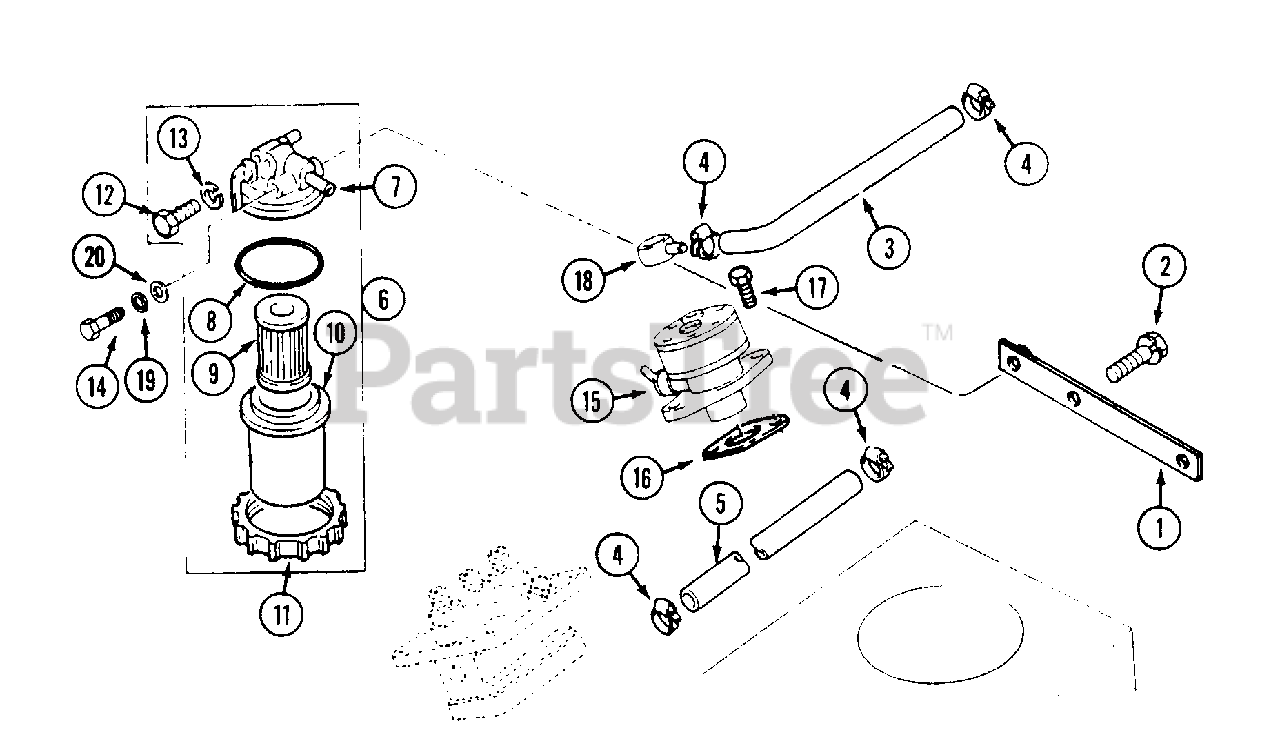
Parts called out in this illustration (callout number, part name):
1	BRACKET - fuel filter mounting
2	SCREW
3	HOSE - fuel (pump to filter) 5.5"
4	CLAMP - hose
5	HOSE - filter to injection pump
6	FILTER ASSEMBLY - fuel
7	HEAD
9	ELEMENT - fuel filter
10	CONTAINER
11	RING
12	PLUG
13	WASHER
14	BOLT - 5/16" - 18 x 2-1/2"
15	PUMP - fuel
16	GASKET
17	SCREW
18	CONNECTOR
19	LOCKWASHER - 5/16"
20	WASHER - 5/16"
